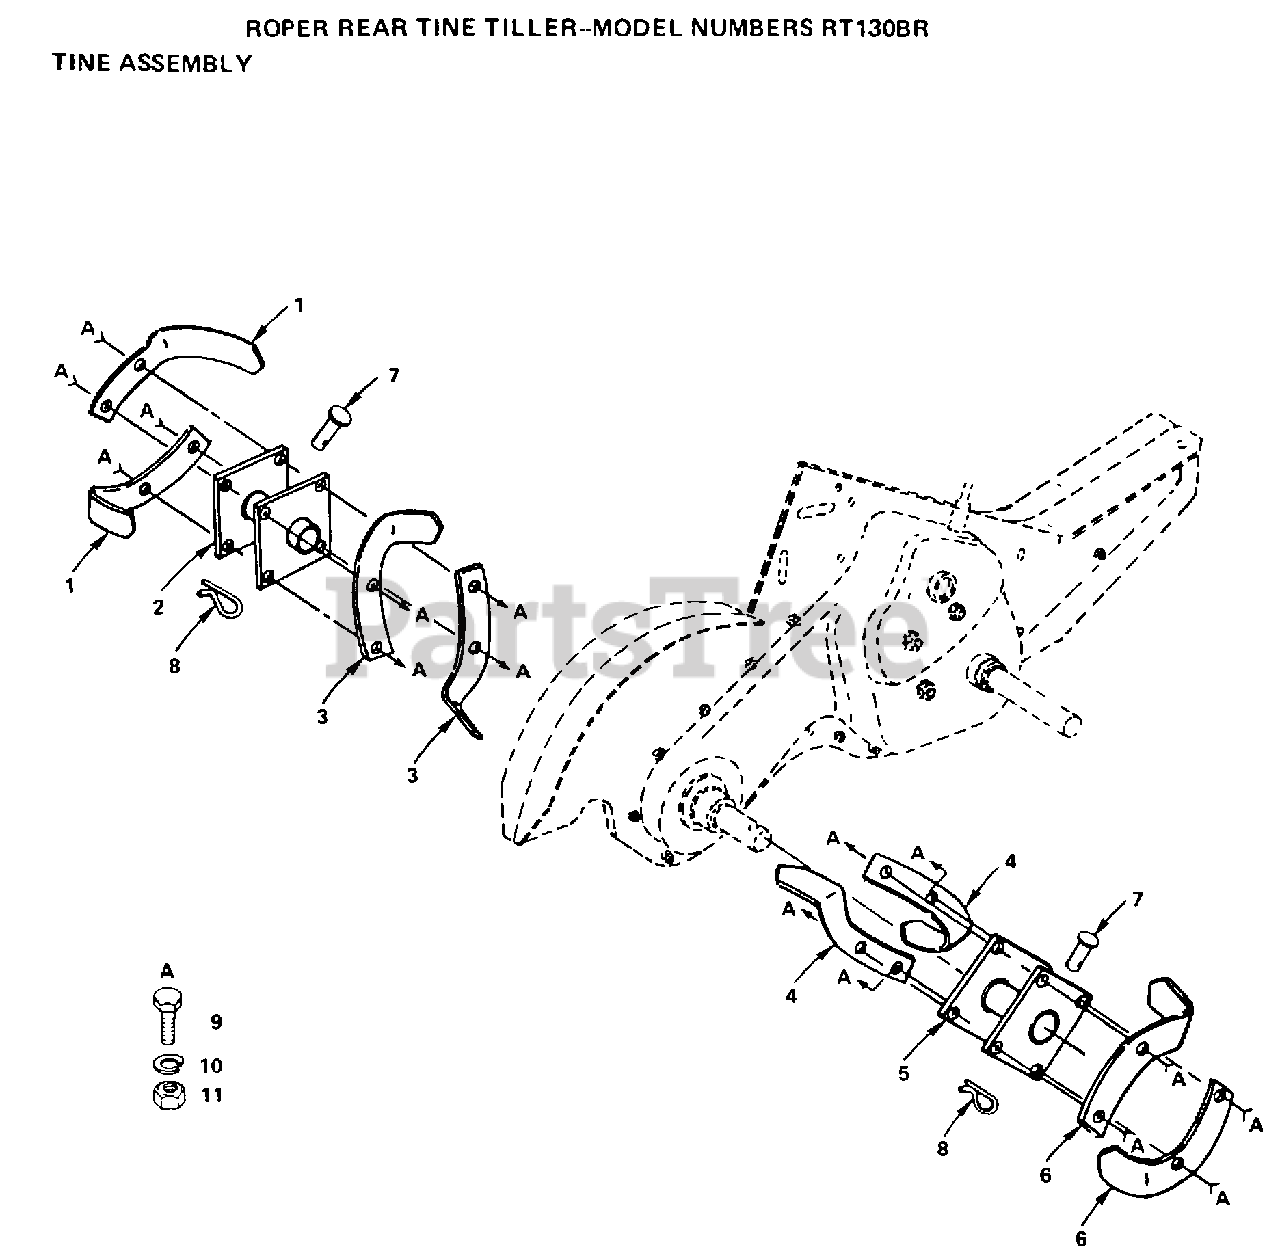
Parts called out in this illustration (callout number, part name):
3	"TINE.LH.12"""
4	"TINE.RH.12"""
7	RIVET.PAN HD.1.75
8	RETAINER.SPRING
9	BOLT
10	LOCKWASHER
